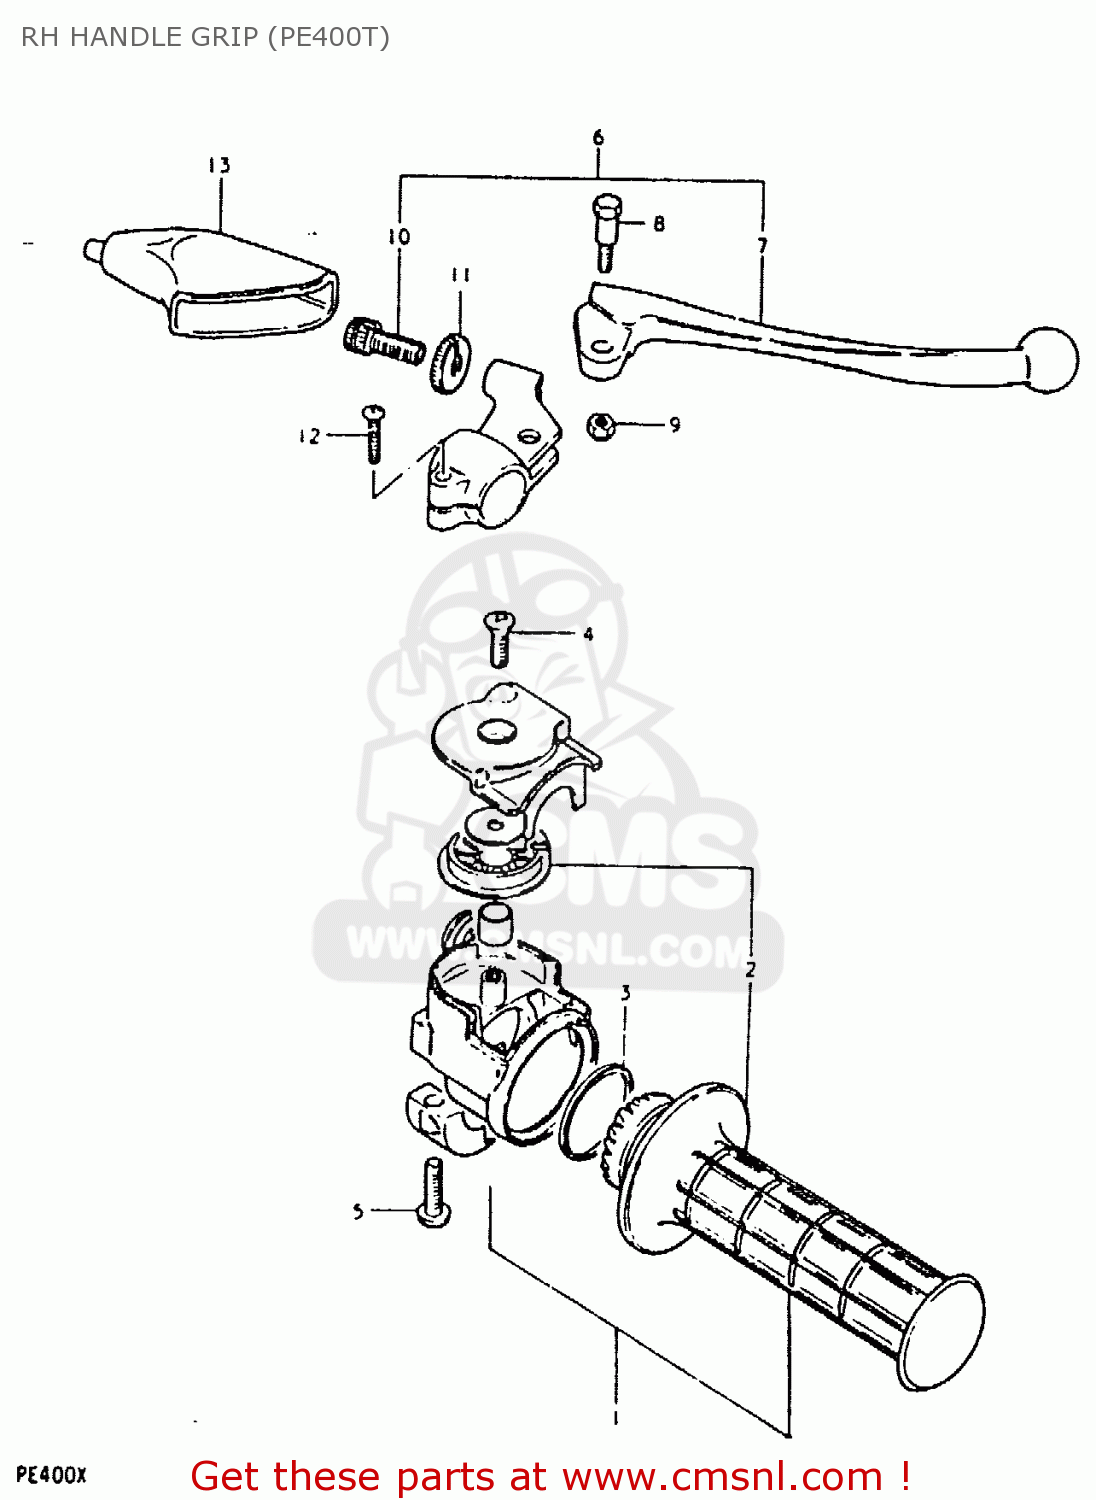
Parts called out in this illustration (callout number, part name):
1	CASE ASSEMBLY,THROTTLE
2	GRIP SET,THROTTLE
3	V-RING,THROTTLE GRIP
4	SCREW
5	SCREW 5X20
6	LEVER ASSY,BRAKE
7	LEVER,BRAKE
8	BOLT,LEVER
9	NUT 6MM
10	ADJUSTER,CABLE
11	NUT,CABLE ADJUSTER
12	SCREW
13	COVER,CLUTCH LEVER
